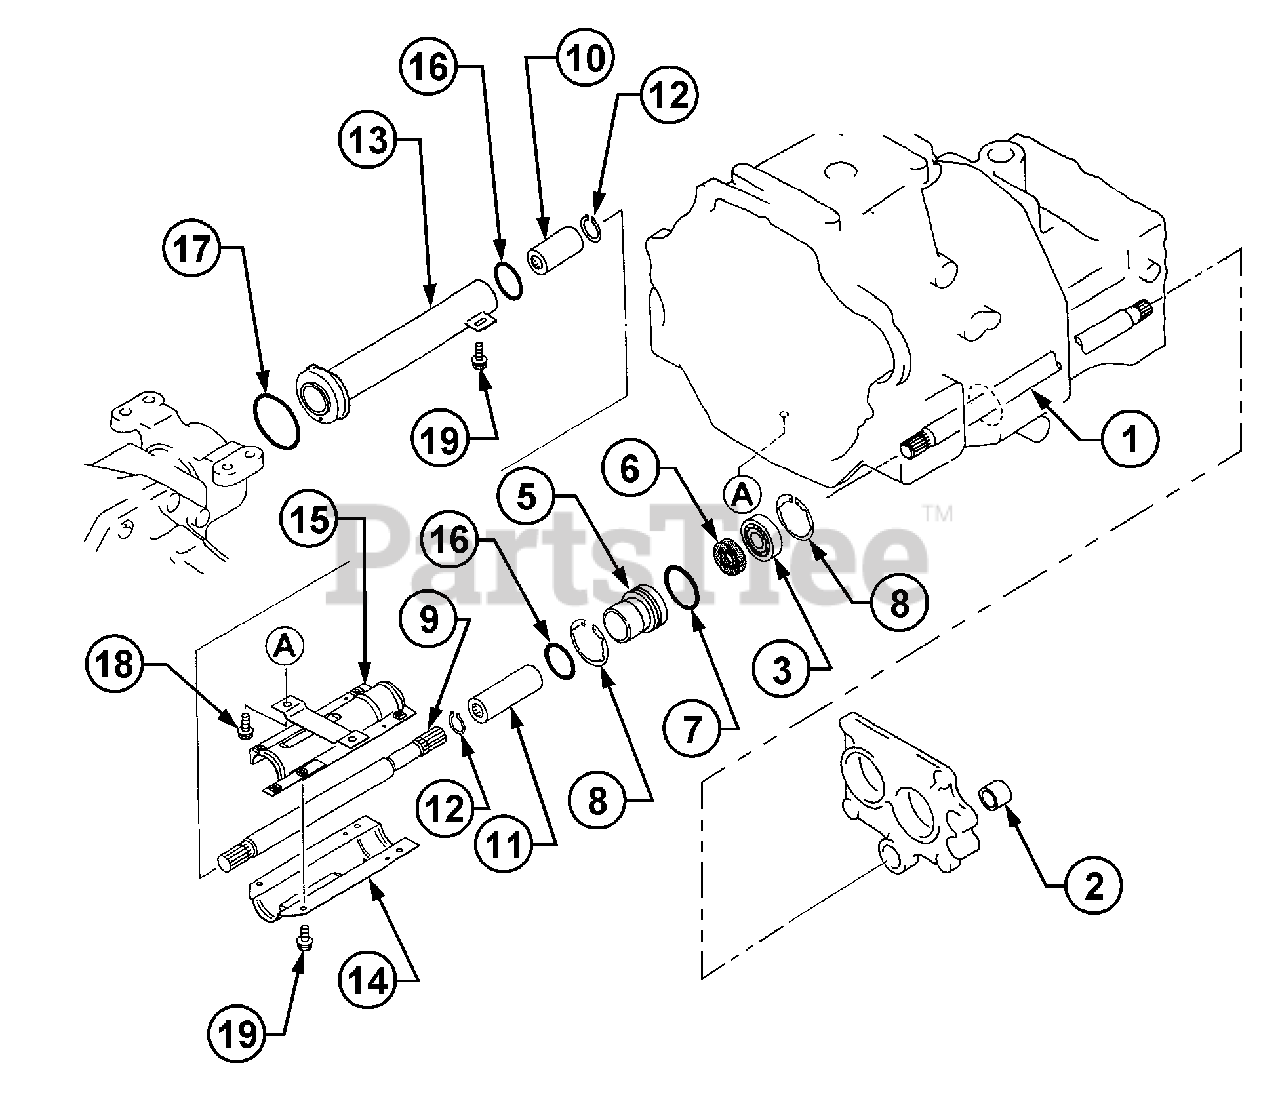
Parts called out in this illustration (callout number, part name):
3	Bearing, Ball
9	Shaft
10	Joint, Front
11	Joint
18	Bolt, w/Washer
19	Bolt, w/Washer
